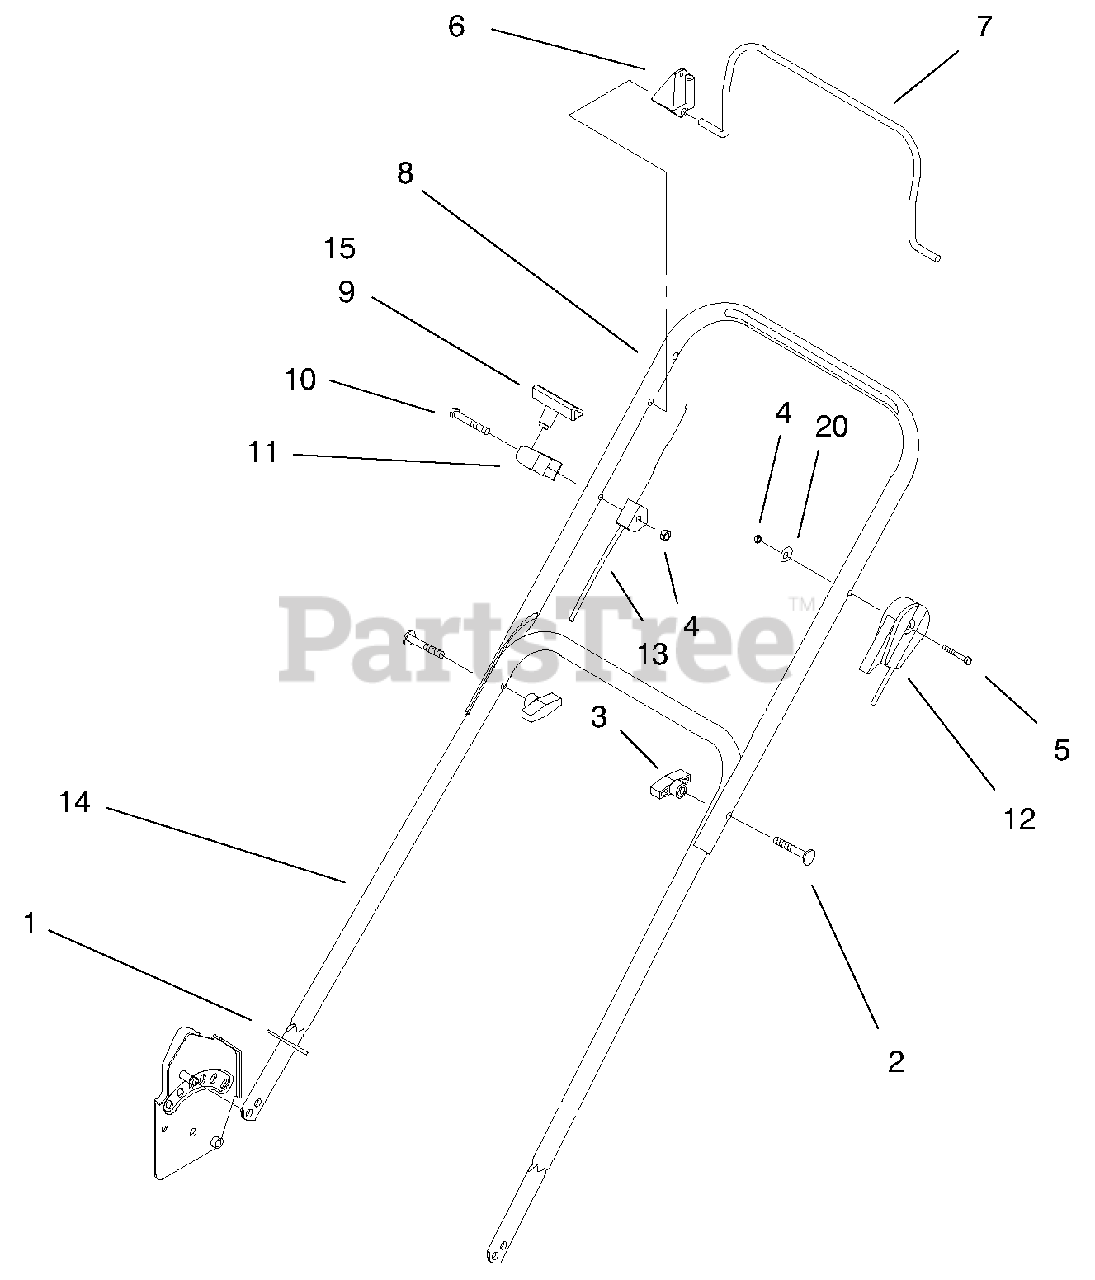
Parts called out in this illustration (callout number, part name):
1	Guard-Handle
2	Screw-HH
3	Knob-Handle
4	Nut-Lock Ni
5	Screw-HH
6	Stop-Pivot
7	Bail-Brake
8	Handle-Upper
9	Handle-Start Eat
10	Screw-HH
11	Rope-Guide
12	Cable-Throttle
13	Cable-Flywheel Brake Hi-Wheel 2 Cyc
14	Section-Lower Handle
15	Starter-Clip Eat
20	Washer
